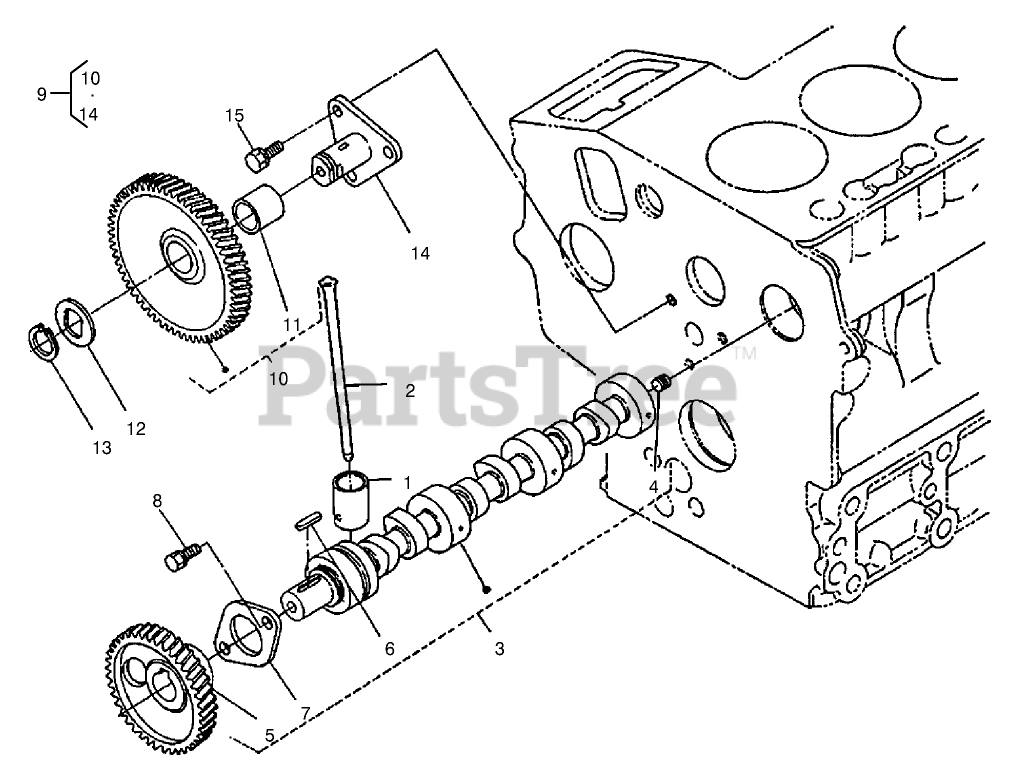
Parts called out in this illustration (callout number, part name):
1	TAPPET
2	ROD-PUSH
3	CAMSHAFT ASM
4	SCREW-SET
5	GEAR-CAM
6	KEY-FEATHER
7	STOPPER-CAMSHAFT
9	IDLE GEAR ASM
10	GEAR-IDLE
11	BUSHING
12	COLLAR-GEAR, IDLE
13	RING-SNAP
14	SHAFT-GEAR, IDLE
